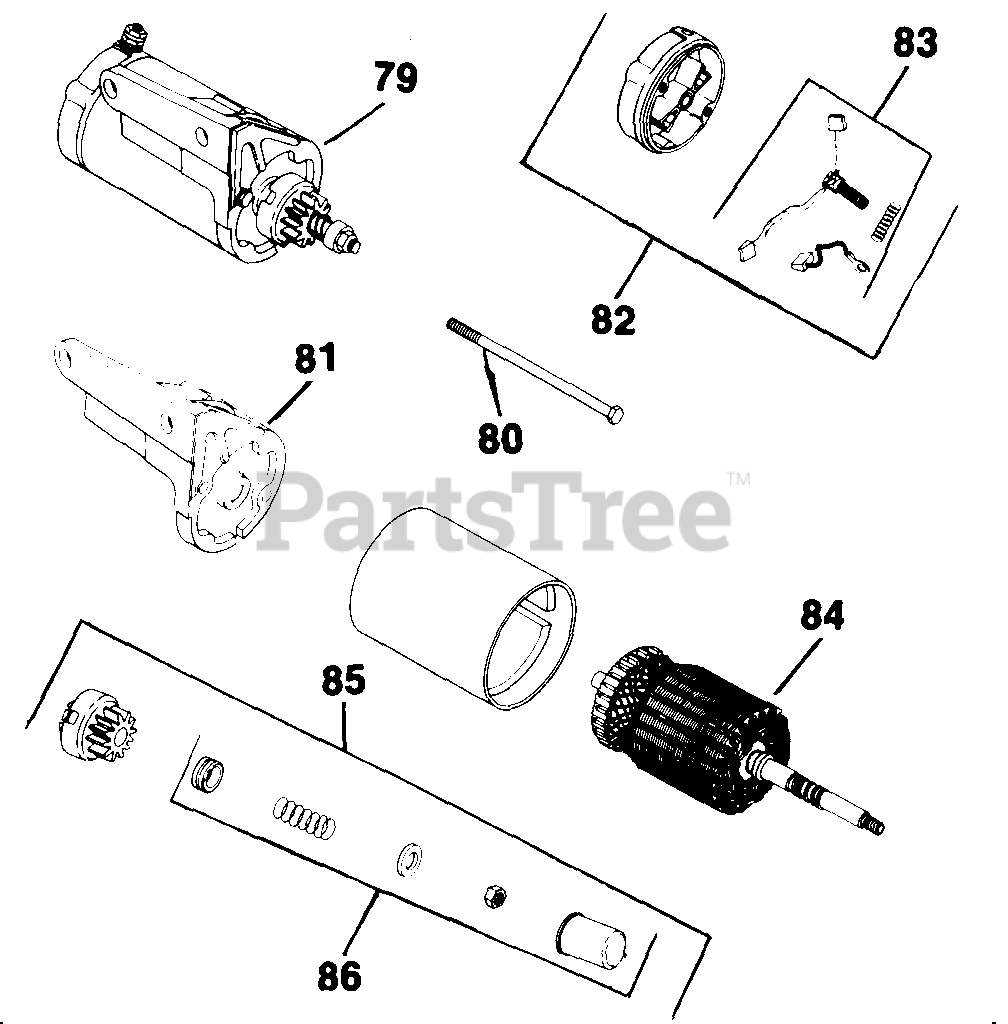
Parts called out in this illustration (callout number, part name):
79	STARTER - USE 45 098 10
80	SCREW - USE 12 086 02
81	BRACKET - DISCONTINUED
82	CAP - DISCONTINUED
83	KIT - USE 52 755 15
